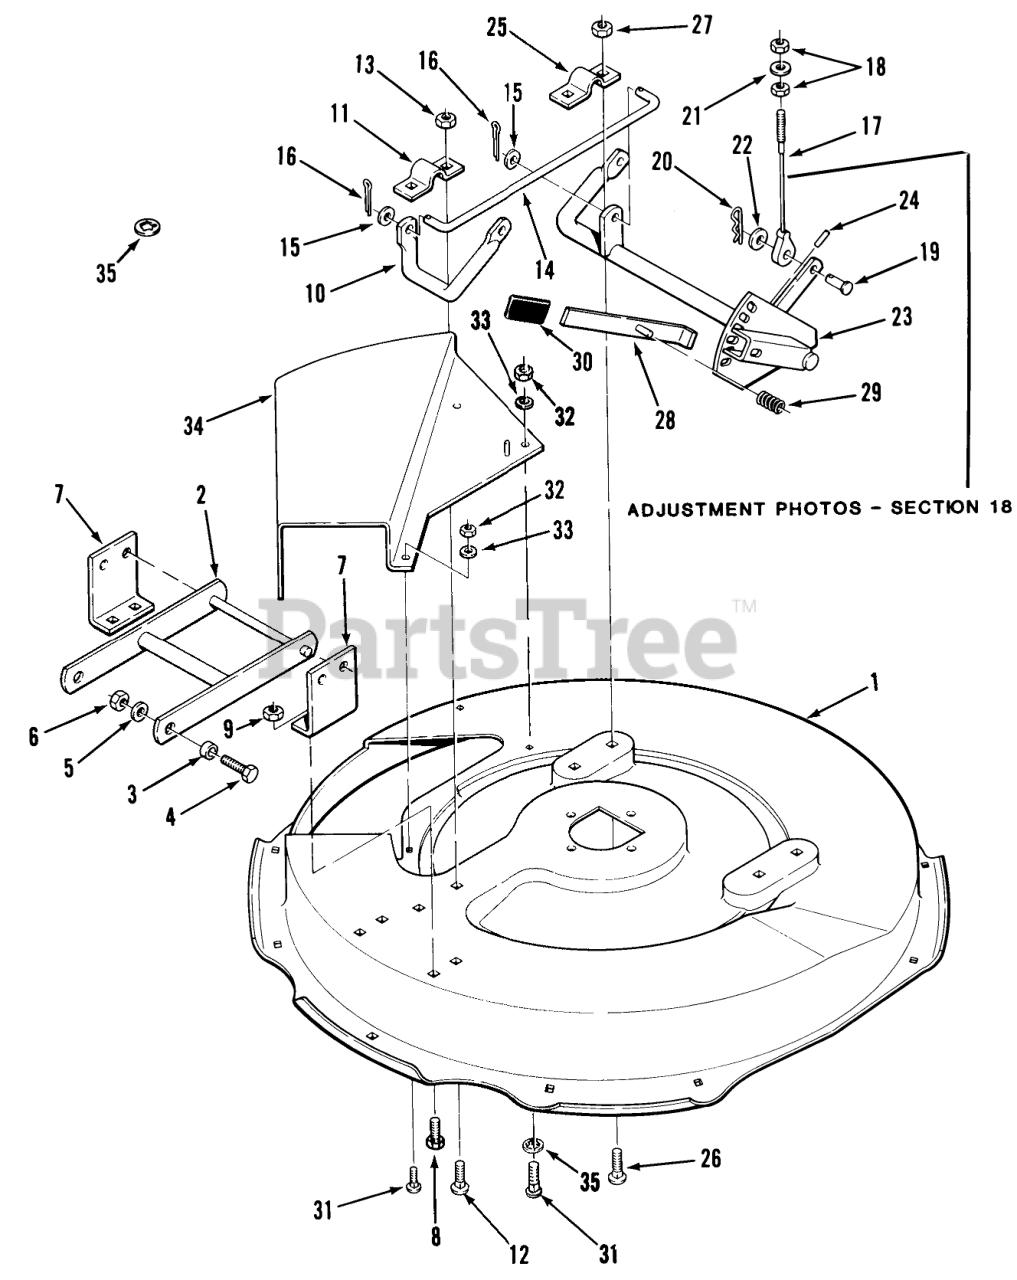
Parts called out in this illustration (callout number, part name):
1	DECK 30" MOWER R
2	ASSY MWR FRONT MO R
3	SPACER
4	BOLT
5	Washer
6	NUT
7	BRKT FRONT MOWER R
8	BOLT
9	NUT
10	ROD HEIGHT ADJ R
12	Bolt
13	NUT
14	ROD HEIGHT ADJUST
15	Washer
16	Cotter Pin
17	CABLE MOWER SUPPORT
18	Nut
19	CLEVIS PIN
20	Hairpin
21	WASHER 5/16 SAE
22	Washer
23	HEIGHT ADJ ASSY R
24	SPIROL PIN
26	Bolt
27	NUT
28	LEVER ASSY
29	SPRING-COMPRESSION
31	Bolt 1/4-20 X 5/8
32	Nut
34	Mower Deflector
35	Washer-Lock
